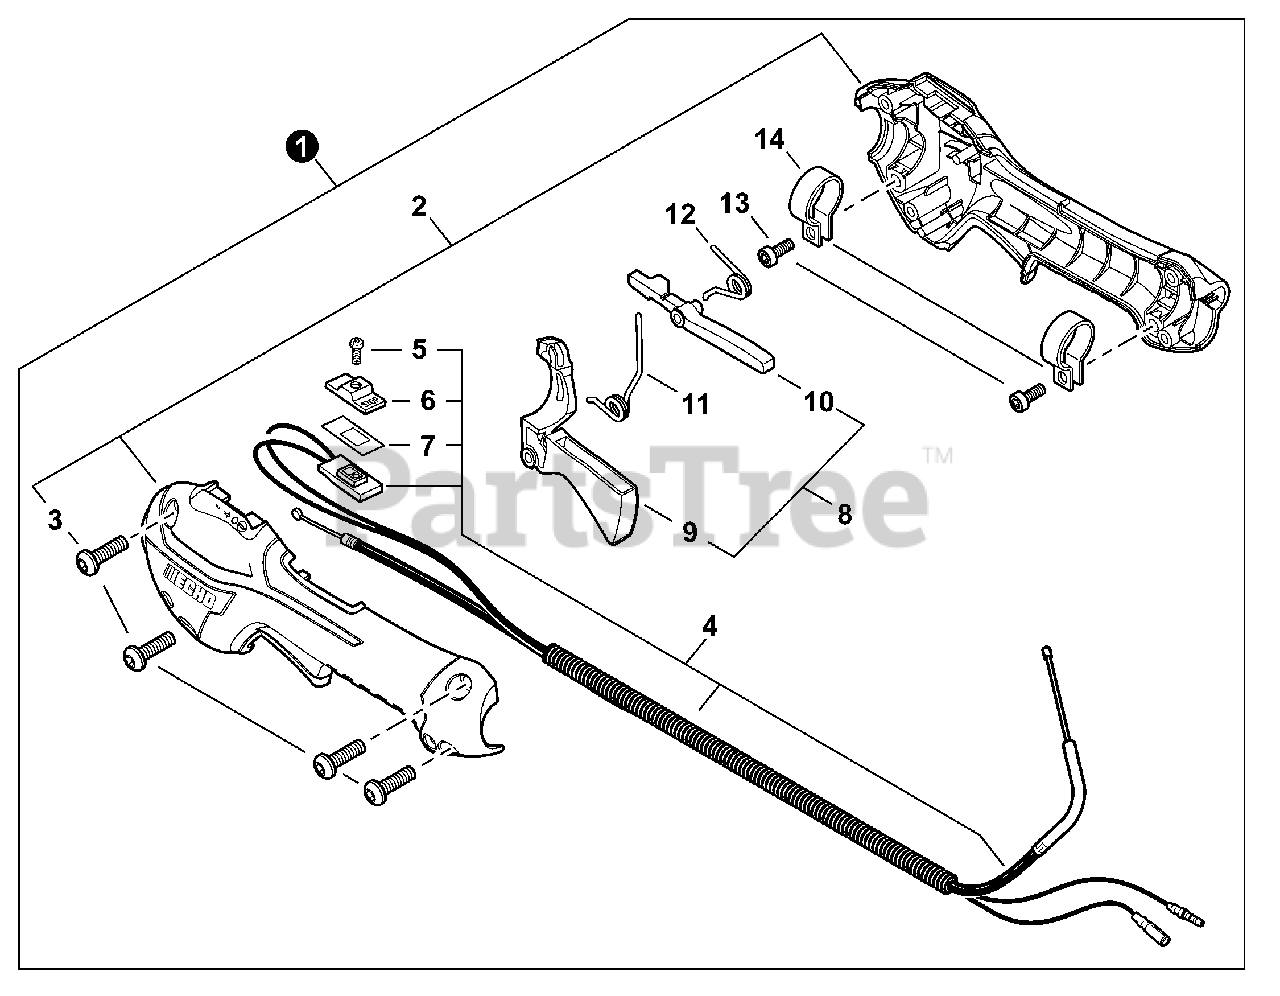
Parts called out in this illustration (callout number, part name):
1	CONTROL HANDLE ASSY
2	CONTROL HANDLE KIT
3	BOLT, TORX 5×16
4	CABLE ASSY, CONTROL
5	SCREW 3×10
6	KNOB, SWITCH - ORANGE
7	SEAL, SWITCH
8	THROTTLE LOCKOUT KIT
9	TRIGGER, THROTTLE
10	LEVER, THROTTLE LOCKOUT
11	SPRING, TORSION
12	SPRING, TORSION
13	BOLT, TORX 5×16
